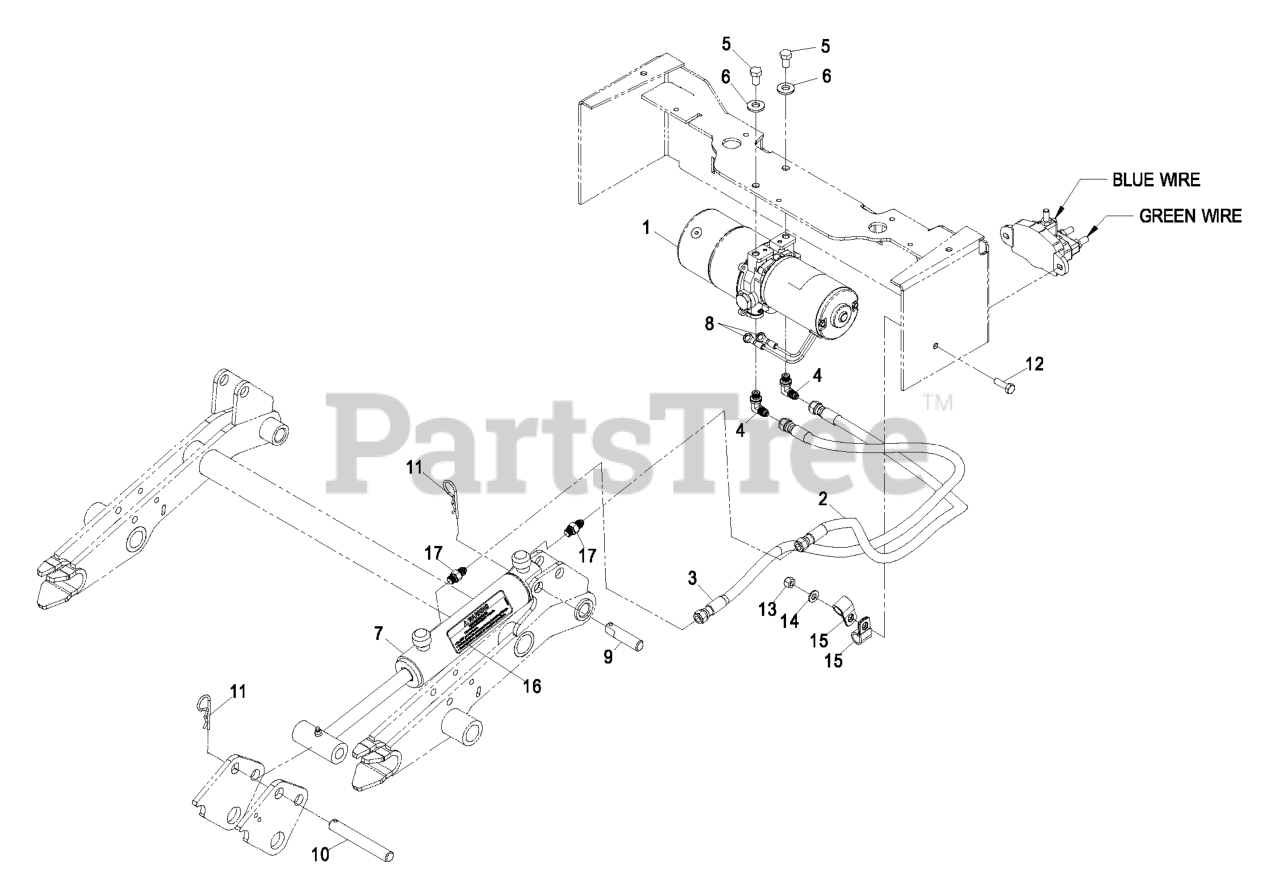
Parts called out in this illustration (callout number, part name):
2	ASM,HYDRAULIC HOSE -4
3	ASM,HYDRAULIC HOSE -4
4	ADAPTER,90 DEG
5	SCREW-HH
6	WASHER-BELLEVILLE
7	ASM,FMZ HYD CYLINDER
8	TERMINAL,RING 5/16" INSUL
9	PIN,CYLINDER MOUNT RR
10	PIN,CYLINDER MOUNT
11	PIN-COTTER
12	SCREW-HH
13	NUT-LOCK, NI
14	WASHER-PLAIN
15	CLIP-LOOM
16	DECAL,HIGH PRESSURE OIL
17	ADAPTER,STRAIGHT ORIFICED
